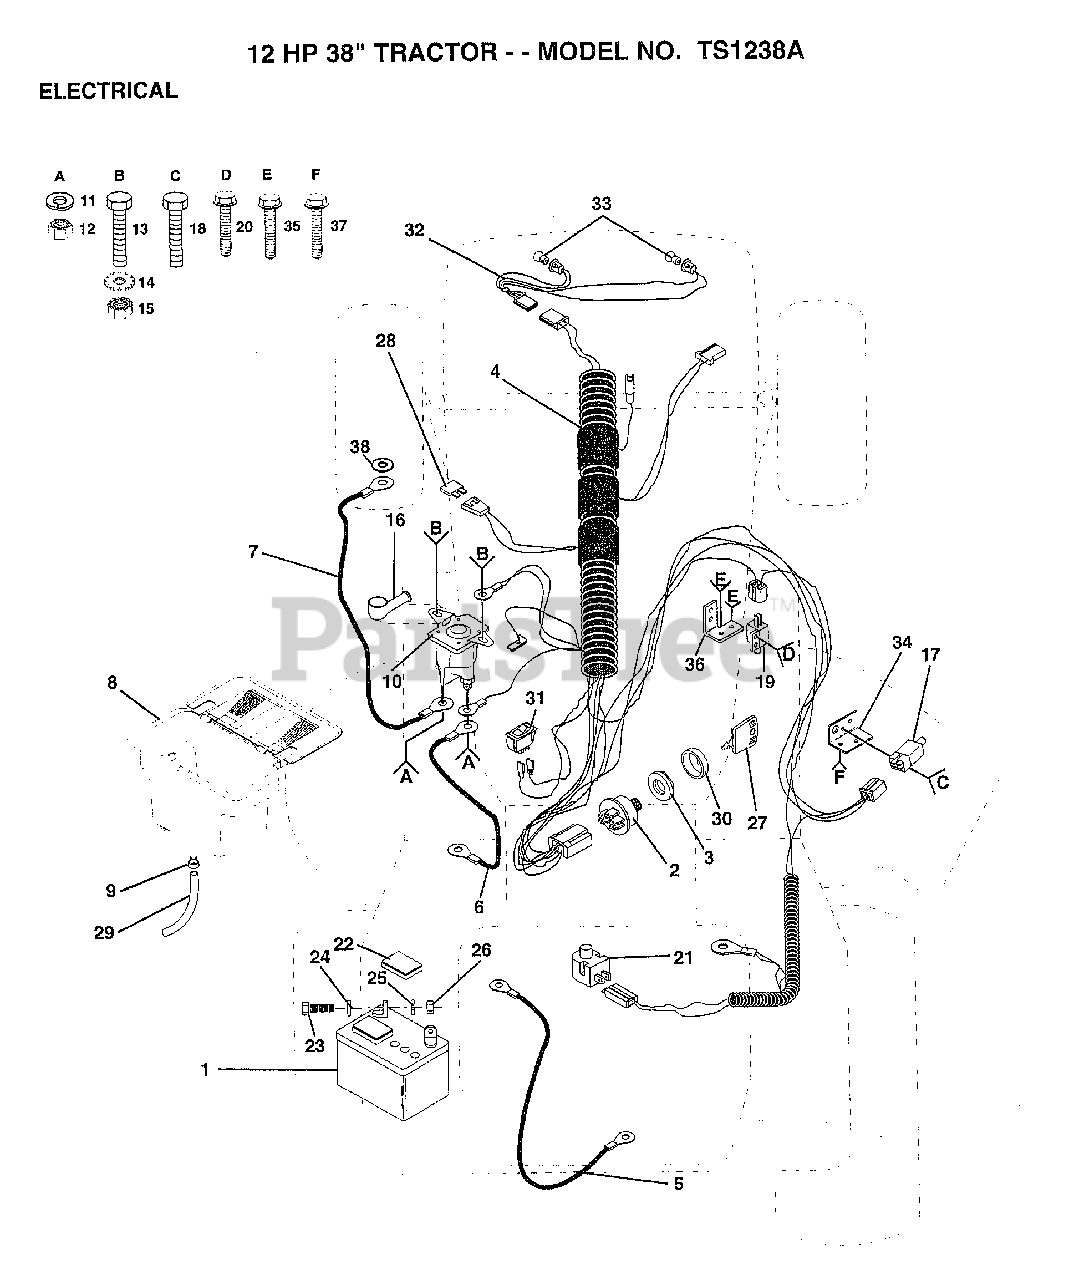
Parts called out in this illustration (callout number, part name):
3	NUT IGNITION
4	IGN HARNESS
5	CABLE T
7	"CABLE T, BATTERY"
9	HOSE CLAMP T
12	NUT
13	BOLT
15	NUT
17	SWITCH INTERLOCKT
18	SCREW
19	SWITCH-INTER. GT
20	SCREW
21	SWITCH SEAT
22	"CAP,BATTERY "
23	BOLT LT
24	WASHER
25	LOCKWASHER
28	FUSE HYT
29	TUBE T
31	SWITCH LT
32	"HARNESS,LIGHT SOC"
33	HEADLAMP BULB
34	SWITCH BRACKET
35	SCREW
36	BRACKET LT
37	SCREW
38	LOCKWASHER
39	SCREW LT
40	CLIP T
